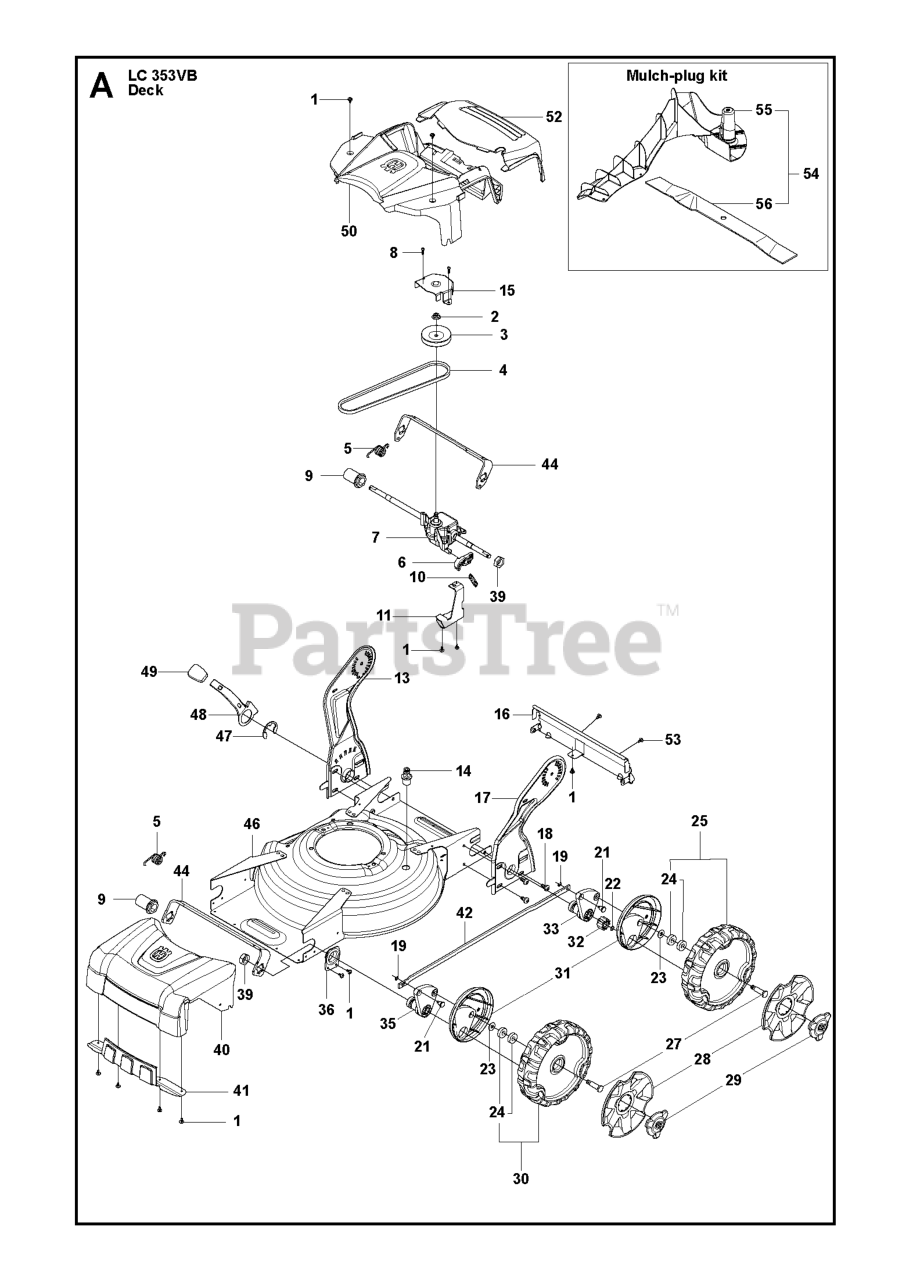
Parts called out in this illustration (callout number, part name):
1	SCREW ITXPANTT M5X10 ZPB (A00
4	BELT WRAPPED V-BELT Z 31 3/4"
8	SCREW ITXPANT T50X16 ZN/FE (A
19	FASTENER
24	BALL BEARING
30	WHEEL ASSY 210, IDLE, MEDIUM
53	SCREW ITXPANTT M5X10 ZPB (A00
